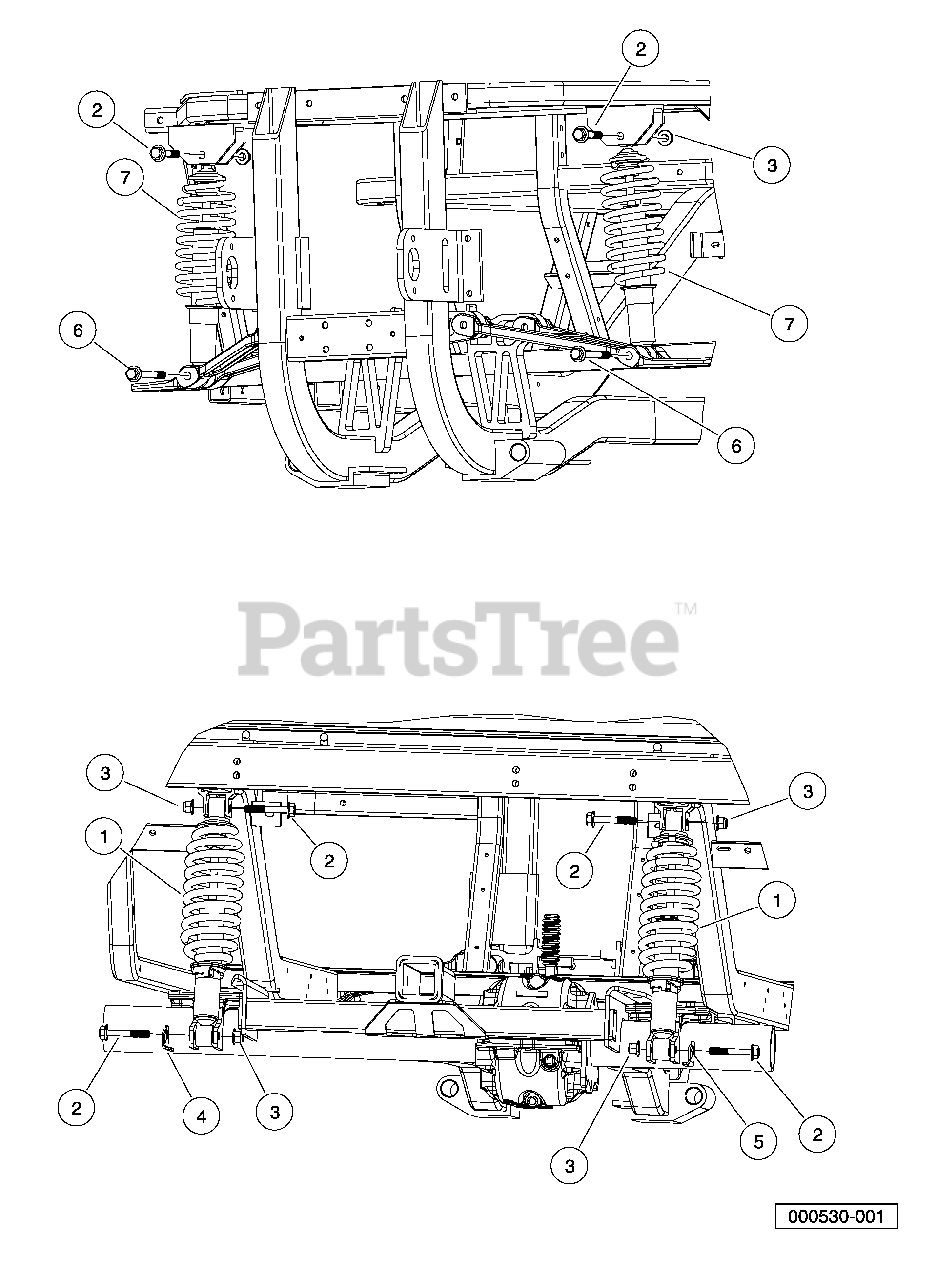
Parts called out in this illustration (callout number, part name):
1	Shock, Coil Over Rear
2	Bolt, Flange Head, M12 X 1.75 X 70
3	Nut Flg, M12x1.75, Nylon Gr 10
4	Brkt, Line, Hyd, Shk Mnt, Drv
5	Brkt, Line, Hyd, Shk Mnt, Pass
6	Bolt Flg, M12x1.75x100, Patch
7	Asm, Coil & Shock, Frt
